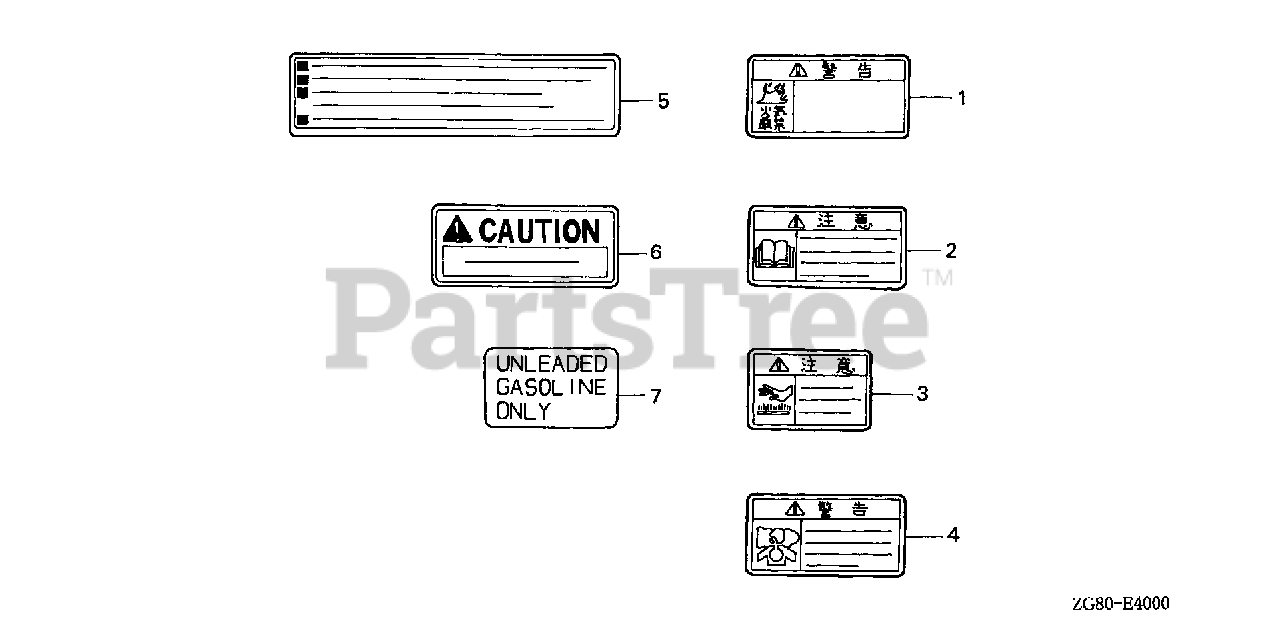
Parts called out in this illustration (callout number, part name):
1	MARK, FUEL WARNING
2	MARK, CAUTION (JAPANESE)
3	MARK, HEAT CAUTION
4	MARK, EX. GAS WARNING
